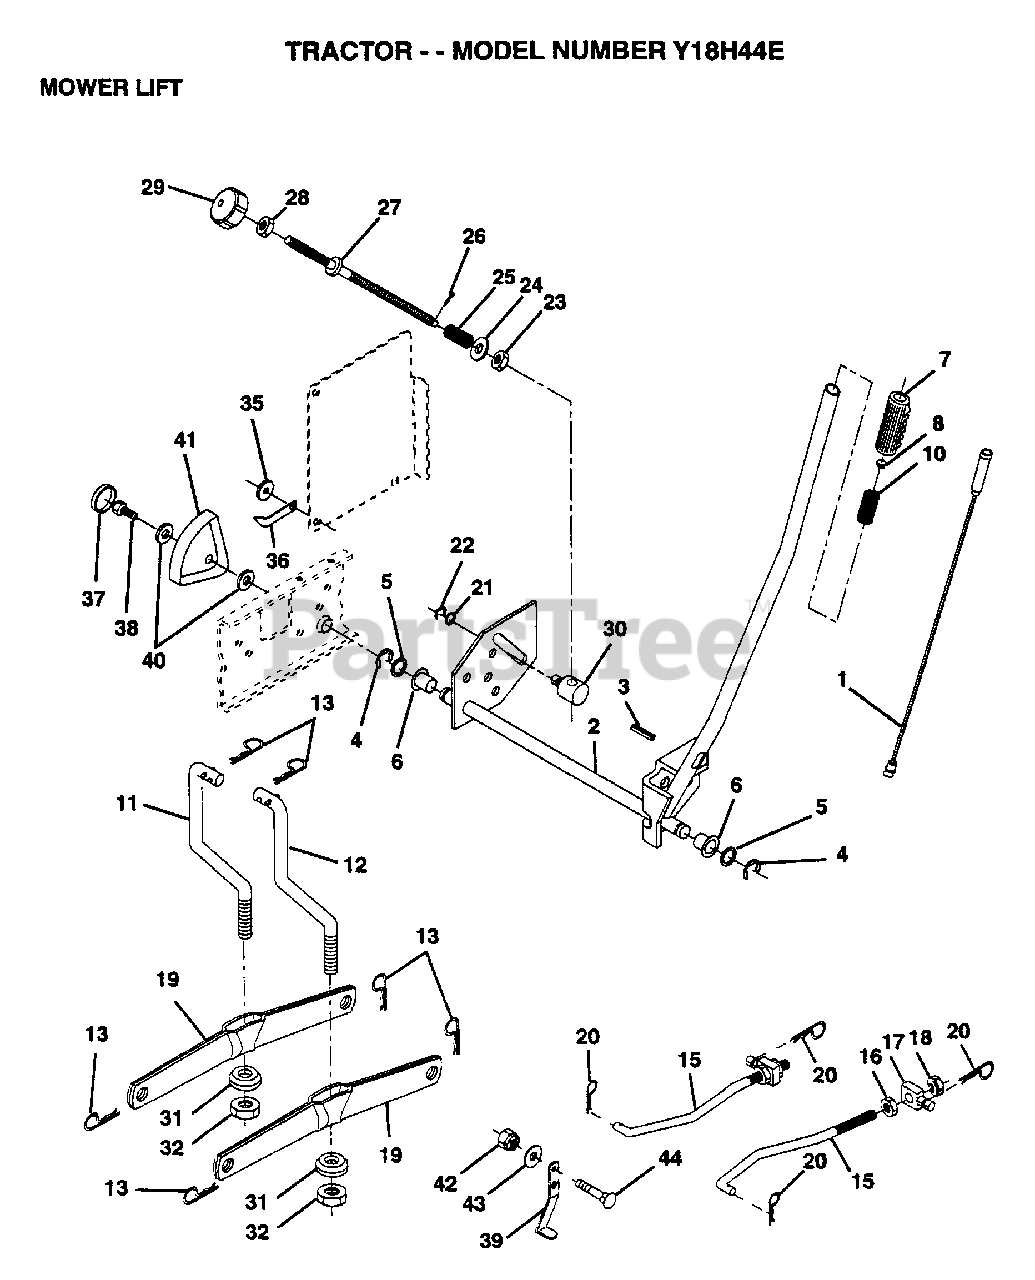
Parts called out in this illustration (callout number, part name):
1	WIRE.ASM.INNER
2	SHAFT.ASM.LIFT.RH
3	PIN GROOVE
5	WASHER
6	NYLON BEARING
7	GRIP
15	LINK.FRONT
16	NUT
17	TRUNION
18	NUT.LK.W/WSH.1/2.
19	ARM SUSP REAR
20	RETAINER.SPRING
21	WASHER
22	KLIP RING
23	NUT T
24	WASHER
25	SPRING.COMP.INF.H
27	ROD.ADJ.LIFT
28	NUT
29	KNOB INF 3/8-16
30	TRUNION LT
31	BEARING PVT LH
32	NUT.CROWNLOCK.3/8
35	WASHER T
36	POINTER HGT IND
37	"PLUG,HOLE"
38	SCREW
39	STOP.OVER.CENTER
40	WASHER
41	HEIGHT INDICATOR
42	NUT
43	WASHER GT
44	BOLT
